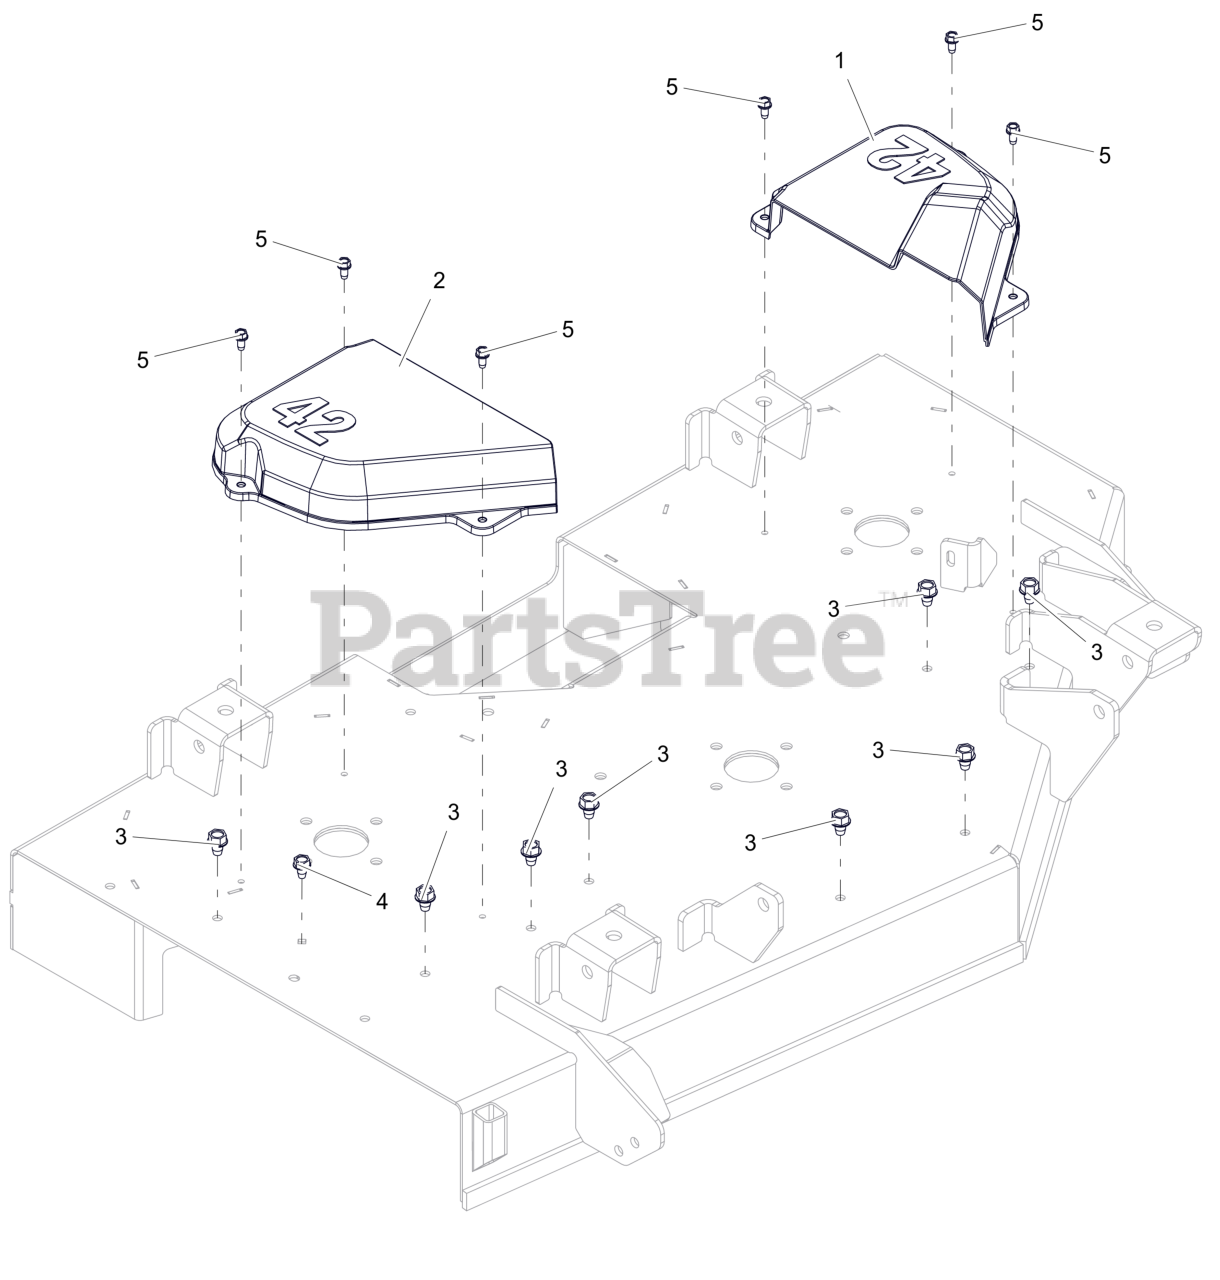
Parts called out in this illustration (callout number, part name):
1	COVER, BELT 42" LH
2	COVER, BELT 42" RH
3	SCR,TAP .375-16X.50 HWH TR ZCC
4	SCR,TAP .312-18X.50 HWH TR ZCC
5	SCR-TAP .25-20X.50 HWH ZCC
